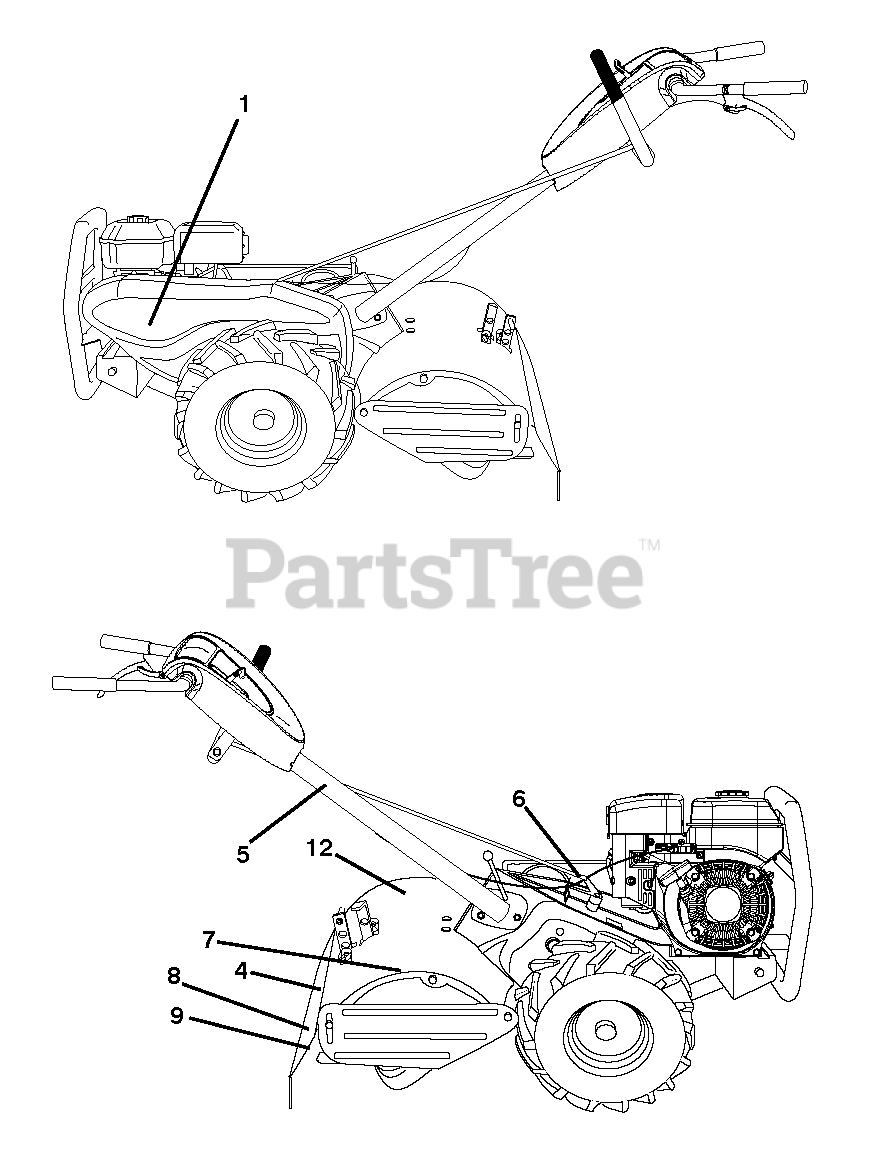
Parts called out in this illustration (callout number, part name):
1	RP.DECAL.BADGE.170MM.TEXTLOGO
4	DECAL.SHIELD.TN.DRT.REAR.SY
5	DECAL.PLACEMENT.HAND.SYMBOLS
6	DECAL.INDICATOR.SHIFT.DRT.SYM
7	DECAL.TILLER.RDIRSYMBL.ORG.HUS
8	DECAL EUROPE STANDARD CE
9	DECAL.WARNING.4-SYM.TILLER.INT
12	DECAL.TILLER.FDIRSYMBL.ORG.HUS
